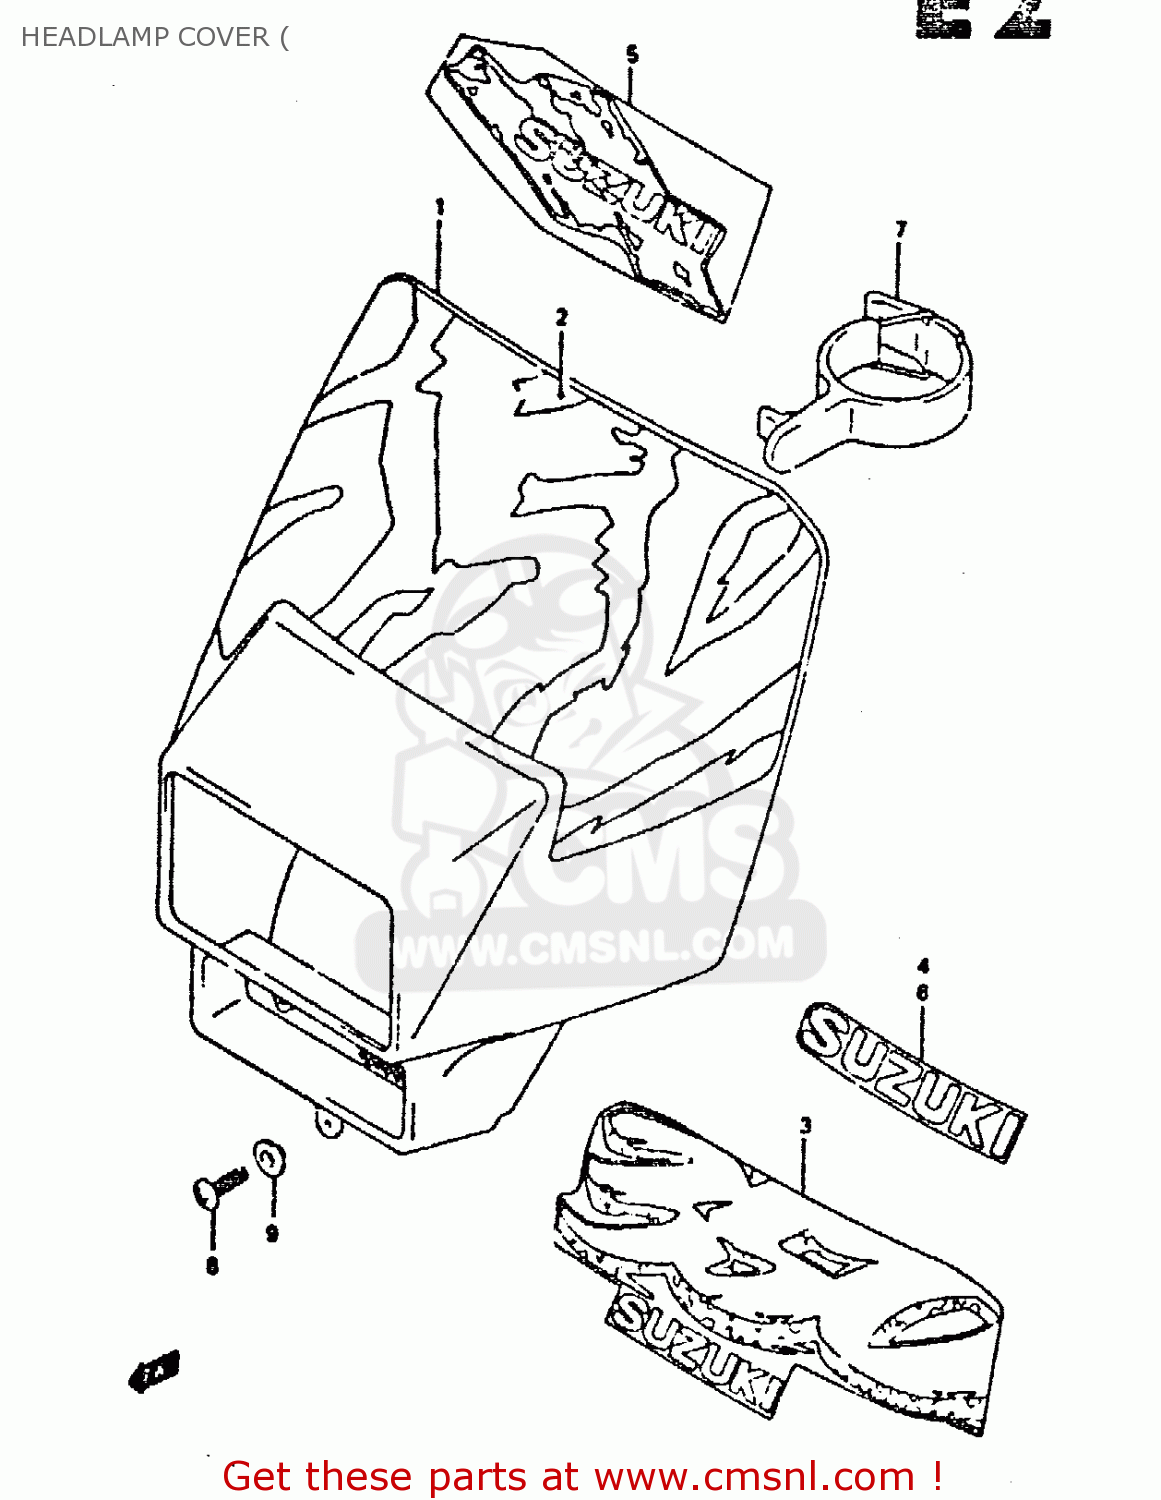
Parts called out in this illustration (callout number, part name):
1	COVER,HEADLAMP
2	TAPE, COVER
3	EMBLEM,HEADLAMP COVER
4	EMBLEM,HEADLAMP COVER
5	TAPE,HEADLAMP COVER
6	EMBLEM,SUZUKI
7	BAND,HEADLAMP COVER
8	SCREW(5X12)
9	WASHER
